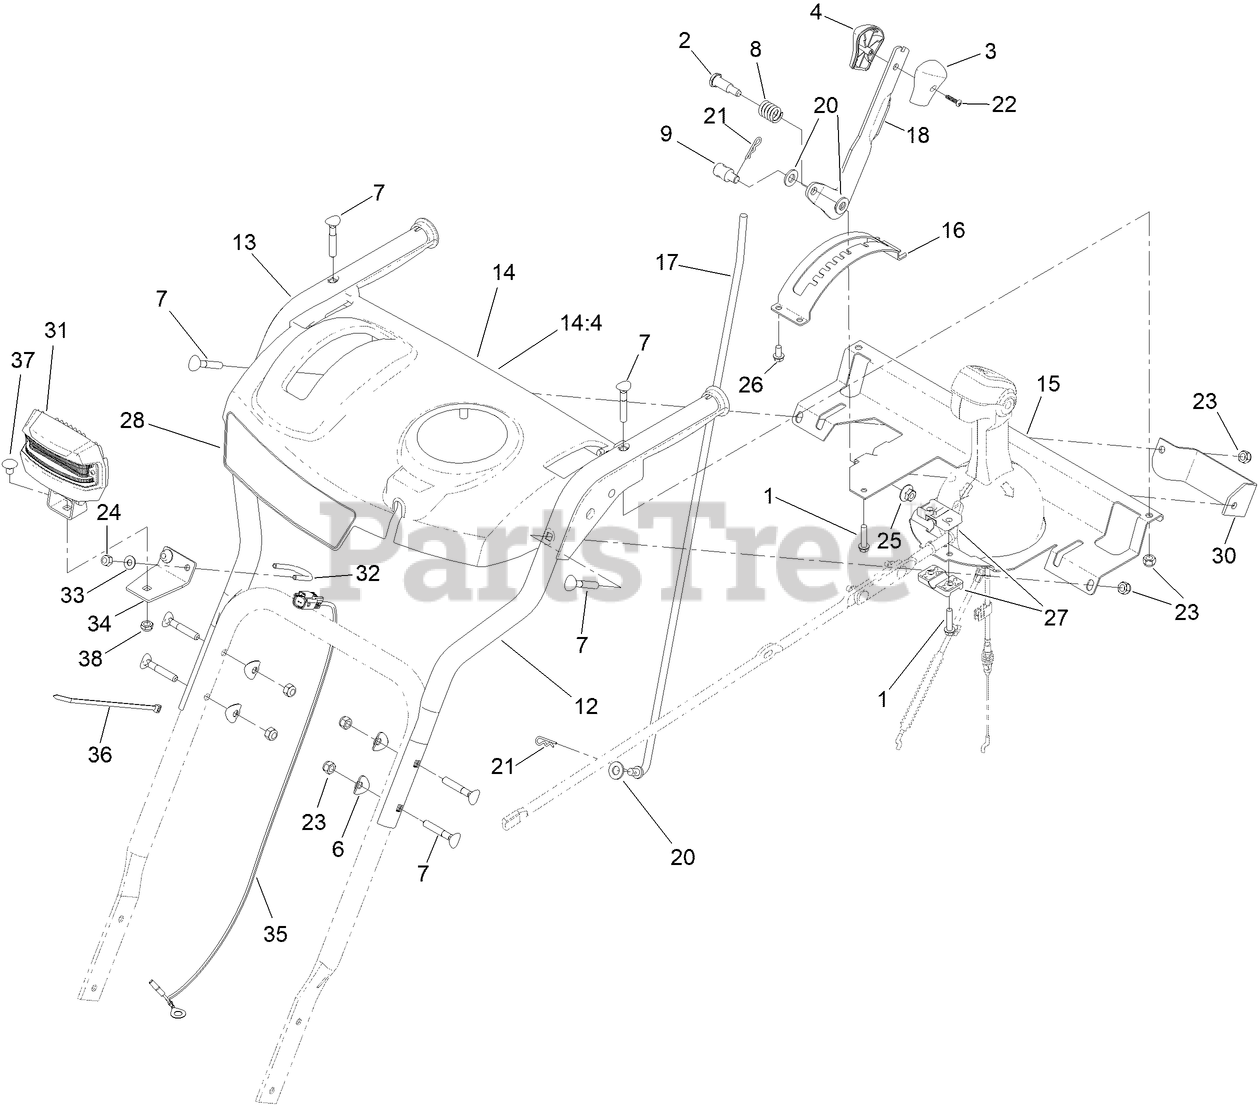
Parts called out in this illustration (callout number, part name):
1	SCREW-PLASTIC,HWH
2	SCREW-SHOULDER, HH
3	KNOB-SHIFT, LH
4	KNOB-SHIFT, RH
6	WASHER-CUP
7	SCREW-HANDLE
8	SPRING-COMPRESSION
9	TRUNNION-ROD
12	HANDLE-UPPER, LH
13	HANDLE-UPPER, RH
14	CONTROL PANEL ASM
14:4	DECAL-SAFETY
15	SUPPORT-PANEL, CONTROL
16	MOUNT-SELECTOR, SPEED
17	ROD-SELECTOR, GEAR
18	SELECTOR-SPEED
20	WASHER-THRUST
21	PIN-HAIR
22	SCREW-PPH
23	NUT-HEX
24	NUT-HEX
25	NUT-HF
26	SCREW-PLASTITE
27	SUPPORT-ROD
28	DECAL-CONSOLE
30	PLATE-SUPPORT, SHIFT
31	LED LIGHT ASM
32	CLAMP-LIGHT
33	WASHER-PLAIN
34	BRACKET-LIGHT
35	HARNESS-WIRE
36	TIE-CABLE
37	BOLT-CARR
38	NUT-HEX
